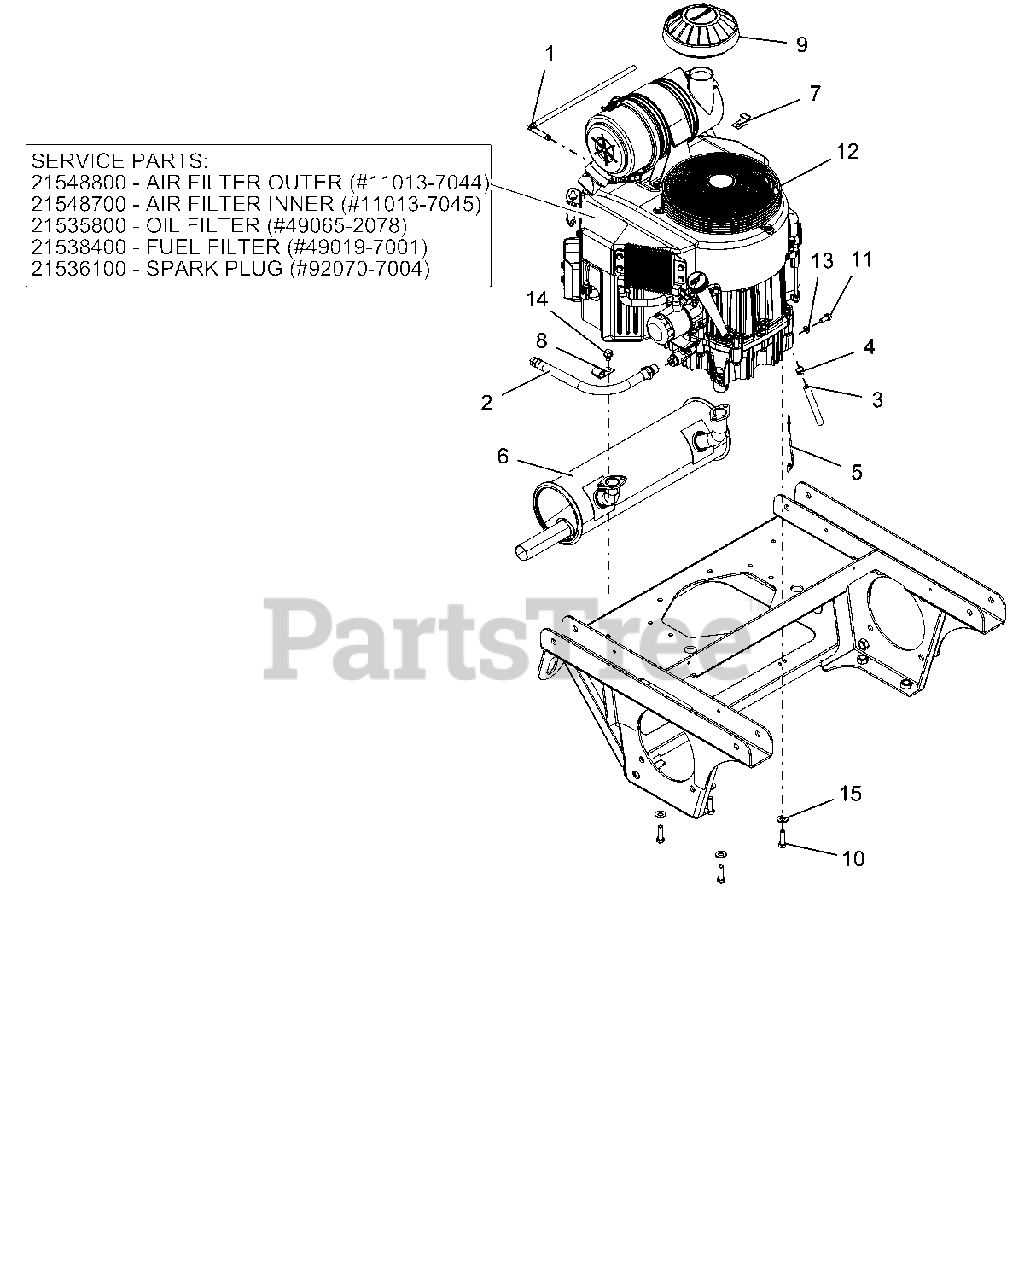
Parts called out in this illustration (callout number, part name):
1	ASM, VAPOR LINE
2	HOSE, OIL DRAIN
3	HOSE, .25 LOW-PERM BULK GAS
4	CLAMP, FUEL LINE
5	LEAD - STARTER SOLENOID
6	MUFFLER, 27-31 KAW
9	CAP, AIR CLEANER INTAKE (2")
10	BLT-HEX.38-16X1.25 G5YZ NYTORQ
11	@BLT-HEX M8-1.25X20 YWZC
12	FILTER,OIL - KAW
12	PLUG, SPARK
12	FUEL FILTER - KAWASAKI
12	FILTER, OUTER
12	FILTER, INNER - KAW
12	ENGINE, KAWASAKI FX850
13	@WSHR-LK .31X.078 REG YWZC
14	@SCR-TAP .38-16X.50 HWH TR YWZ
15	WASHER, 3/8" SPRING DISC
